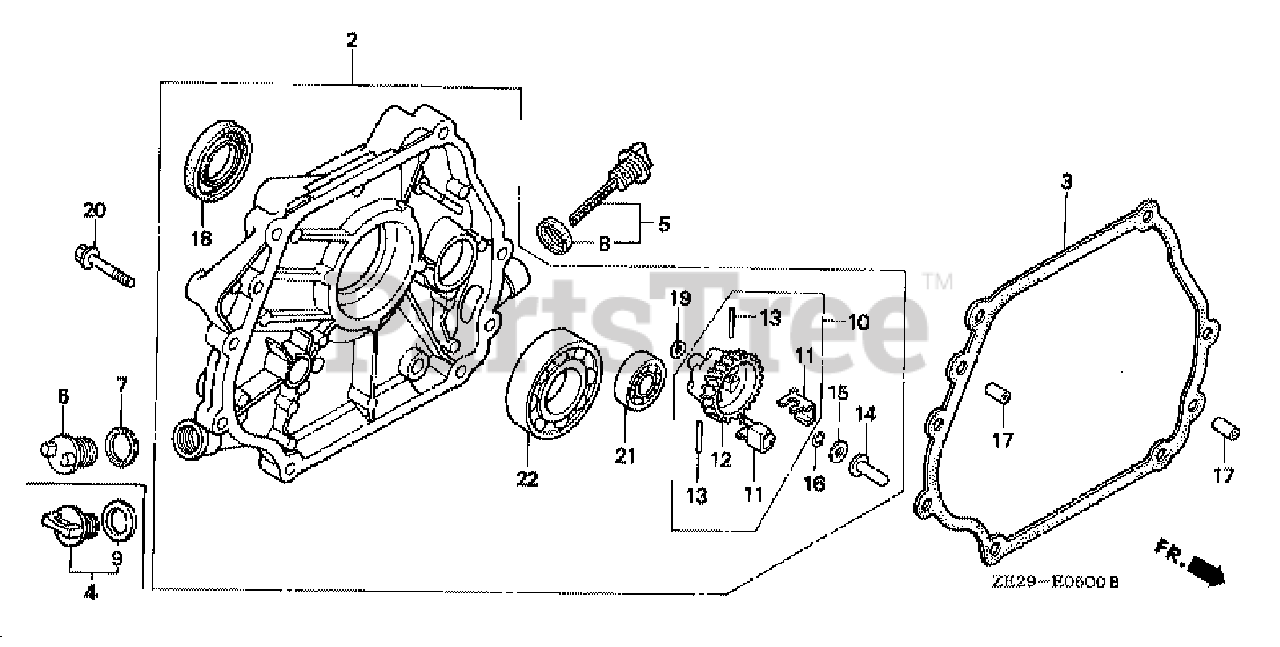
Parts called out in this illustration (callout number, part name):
2	COVER ASSY., CRANKCASE (Q-TYPE)(BALANCER)
3	GASKET, CASE COVER
4	CAP ASSY., OIL FILLER
5	CAP ASSY., OIL FILLER
6	CAP, OIL FILLER
7	GASKET, OIL FILLER CAP
8	GASKET, OIL FILLER CAP
9	GASKET, OIL FILLER CAP
10	GOVERNOR ASSY. (BALANCER)
11	WEIGHT, GOVERNOR
12	HOLDER, GOVERNOR WEIGHT
13	PIN, GOVERNOR WEIGHT
14	SLIDER, GOVERNOR
15	WASHER (6X16)
16	CLIP, GOVERNOR HOLDER
17	PIN, DOWEL (8X12)
18	OIL SEAL (30X46X8)
19	WASHER, PLAIN (6MM)
20	BOLT, FLANGE (8X35)
21	BEARING, RADIAL BALL (6202)
22	BEARING, RADIAL BALL (6206)
